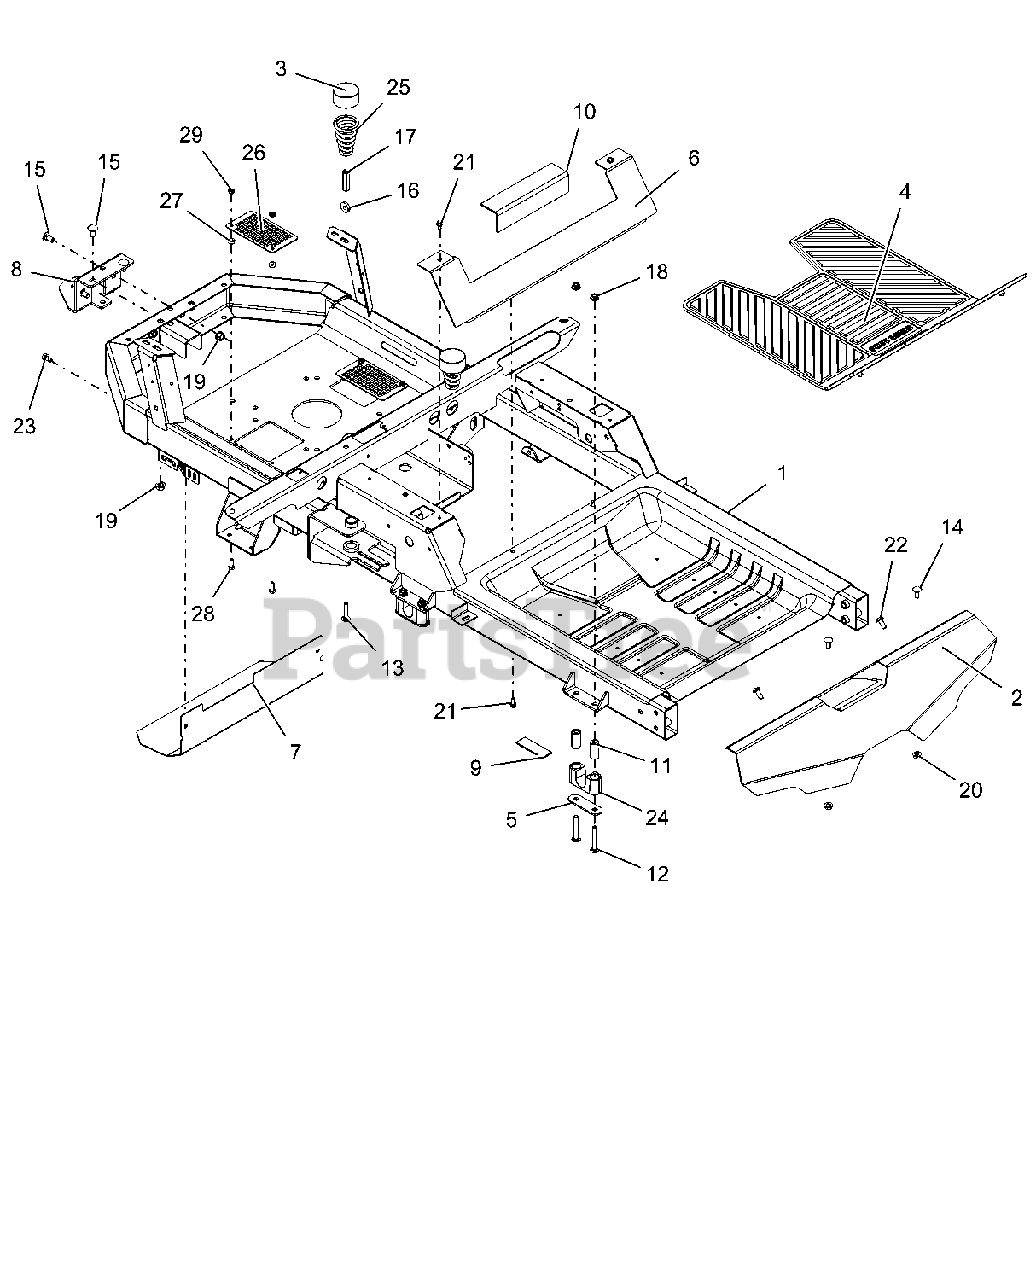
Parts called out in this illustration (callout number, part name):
1	WLDMT, FRAME - 2016 IKON X/XL
2	KIT, FOOTPLATE W/DECAL -IKON
3	HUB CAP
4	FLOOR MAT, RUBBER - ARIENS
5	PLATE, BEARING SUPPORT
6	PLATE, SEAT KICK
7	HEAT, SHIELD
8	BRKT, HITCH TONGUE
9	PAD,RBR 1.0"X3.0" W/ADHESIVE
10	PAD, RUBBER-TANK
11	SPACER, .323 X .698 X 1.441
12	BLT-RDHDSQSHNK .31-18X2.25 YWZ
13	@BLT-RDHDSQNK .31-18X1.50 G5YZ
14	@BLT-RDHDSQNK .31-18X.75 G5YZ
15	@BLT-RDHDSQNK .38-16X.75 G5YZ
16	WSHR-FL-STL .328X.87X.179 YWZC
17	NUT, COUPLING 5/16-18 X 1 3/4
18	@NUT-LK-CTR-FLG .31-18 YZ GR F
19	@NUT-LK-TOP-FLG .38-16 YWZC
20	@NUT-LK-TOP-FLG .31-18 YWZC
21	SCR-TAP .25-20X.50 HWH TR YWZ
22	SCR-RDHDSKTAP .31-18 X .75
23	@SCR-TAP .31-18X.50 HWH TR YWZ
24	BSHG, DECK LIFT PIVOT
25	SPRING, SEAT
26	GUARD, VENT - IKON CE
27	BSHG-SLV .265X.500X.219
28	@BLT-HEX .25-20X.75 GR5 YWZC
29	NUT-LK-CTR JAM .25-20 YWZC
